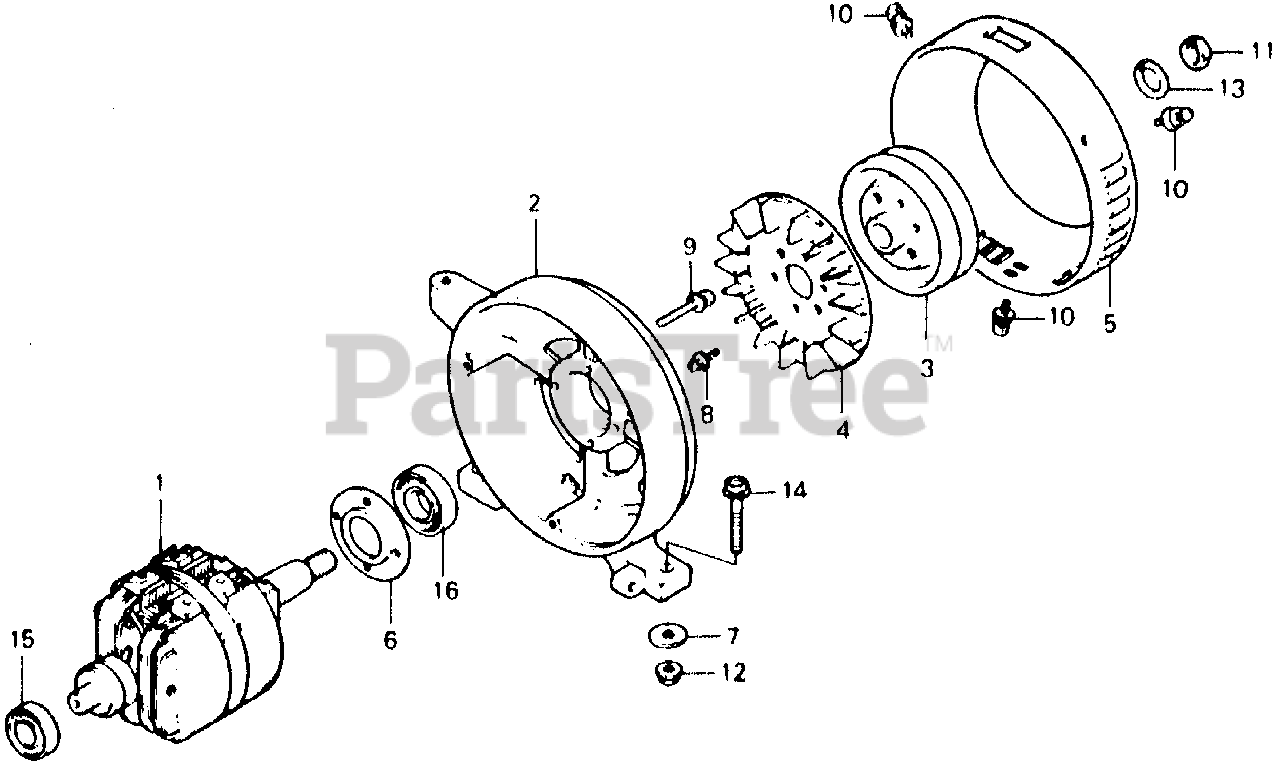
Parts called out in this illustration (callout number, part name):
2	HOUSING, FR. *NH31* (MCKINLEY WHITE)
3	PULLEY, GENERATOR *NH1* (BLACK)
5	COVER, FAN *NH31* (MCKINLEY WHITE)
6	COVER B, BEARING
7	WASHER, EX. MANIFOLD
8	SCREW-WASHER (5X10)
9	SCREW-WASHER (4X25) (NOT AVAILABLE)
10	SCREW-WASHER (5X10)
11	NUT, HEX. (18MM) (NOT AVAILABLE)
12	NUT, FLANGE (10MM)
13	WASHER, SPRING (18MM) (SOURCE: VINTAGE PARTS INC.)
14	BOLT, FLANGE (10X32)
15	BEARING, RADIAL BALL (6203UU)
16	BEARING, RADIAL BALL (6205UU)
